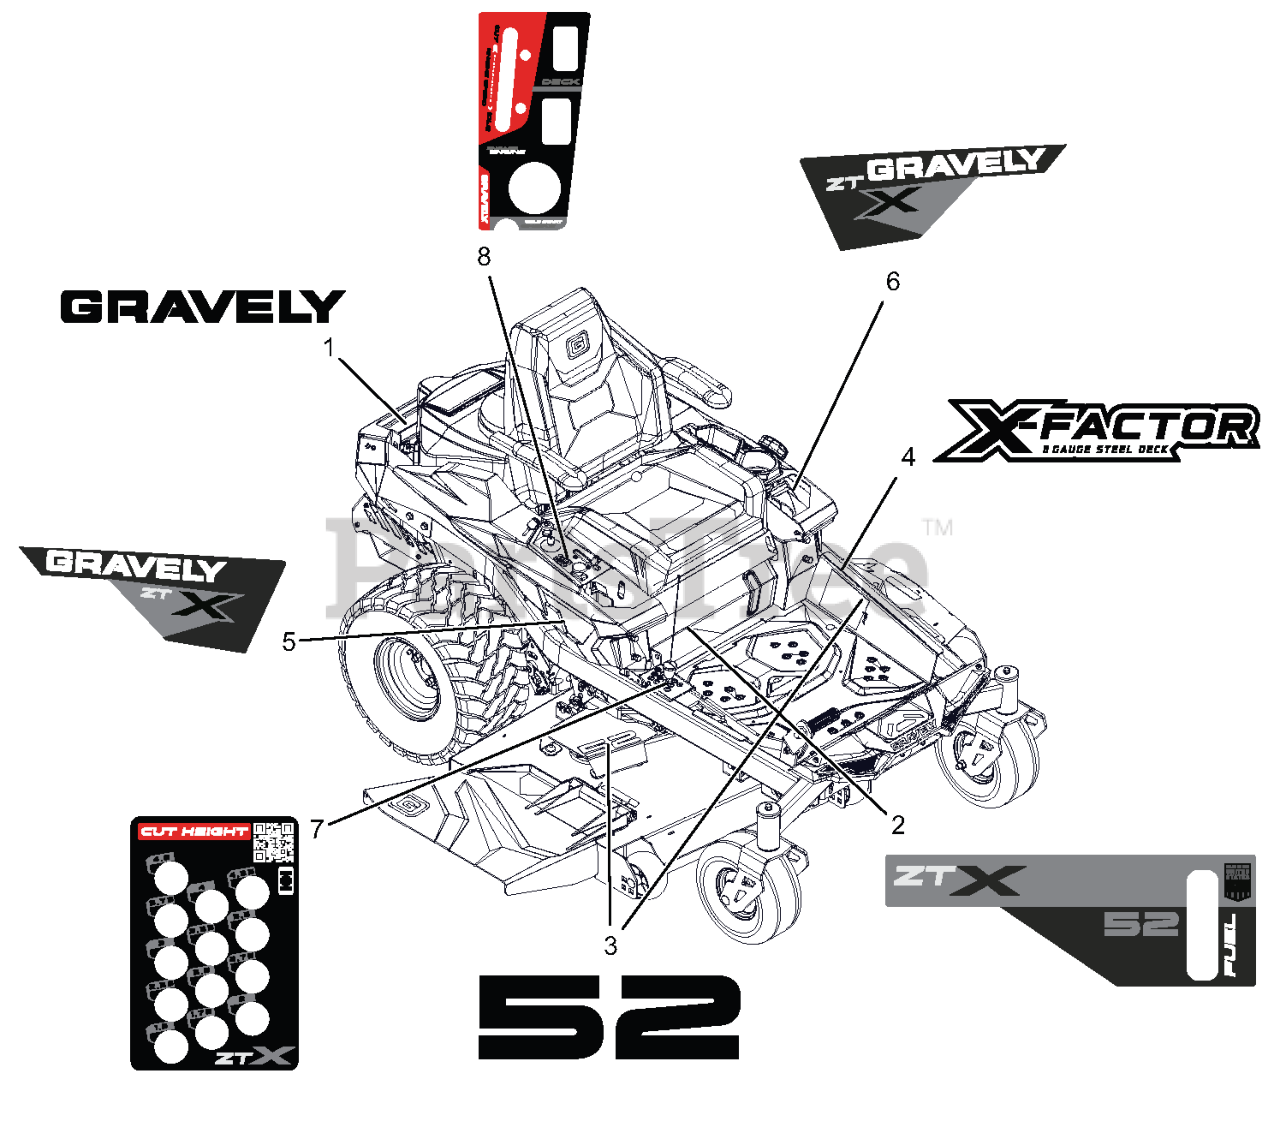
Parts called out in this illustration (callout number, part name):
1	DECAL- GRAVELY
2	DECAL- ZTX 52-KICK PLATE
3	DECAL- DECK 52"
4	DECAL- DECK X-FACTOR
5	DECAL- ZT X FENDER RH
6	DECAL- ZT X FENDER LH
7	DECAL- HEIGHT OF CUT-X
8	DECAL- CONTROL PANEL-GRAVELY
